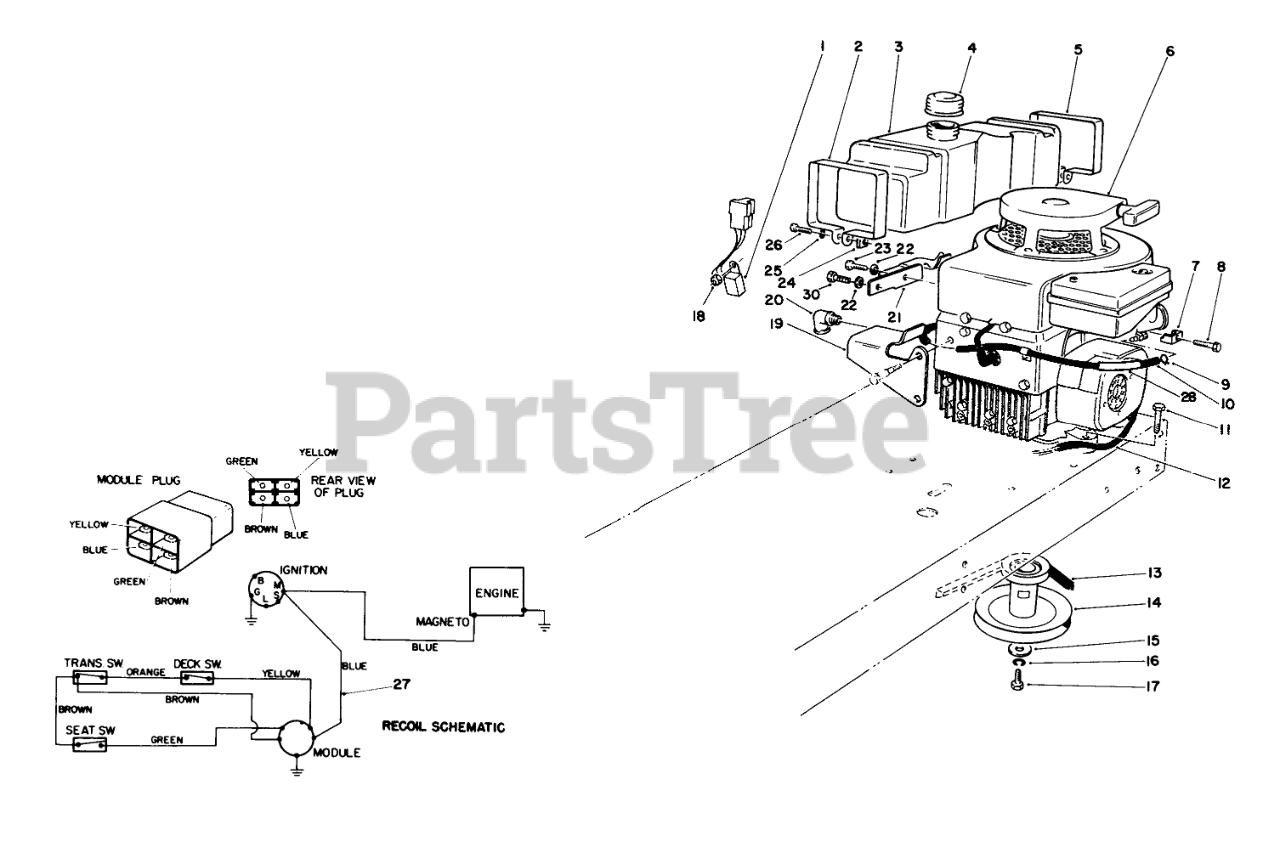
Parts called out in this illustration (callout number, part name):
1	INTERLOCK MODULE
2	Retainer-Front
3	TANK-5 QT GAS
4	GAS CAP ASM
5	Retainer-Rear
6	Engine
7	CLAMP-CASING
8	SCREW W ENGINE
9	CLAMP-HOSE
10	HOSE-FUEL
11	SCREW-HH
12	HEAT SHRINK TUBING
13	V-BELT, TRACTION
14	PULLEY
15	WASHER-FLAT
16	WASHER-LOCK
17	SCREW-HH
18	NUT-LOCK, CONE
19	FRT TANK MTG BRKT B
20	ELBOW-STREET, 90 DEG
21	REAR TANK MTG BRKT B
22	WASHER-PLAIN
23	SCREW-HH
24	NUT-SQUARE
25	WASHER-LOCK
26	SCREW-HSH
27	Wire Harness
28	SUPPORT-FUEL LINE
30	SCREW-HH
